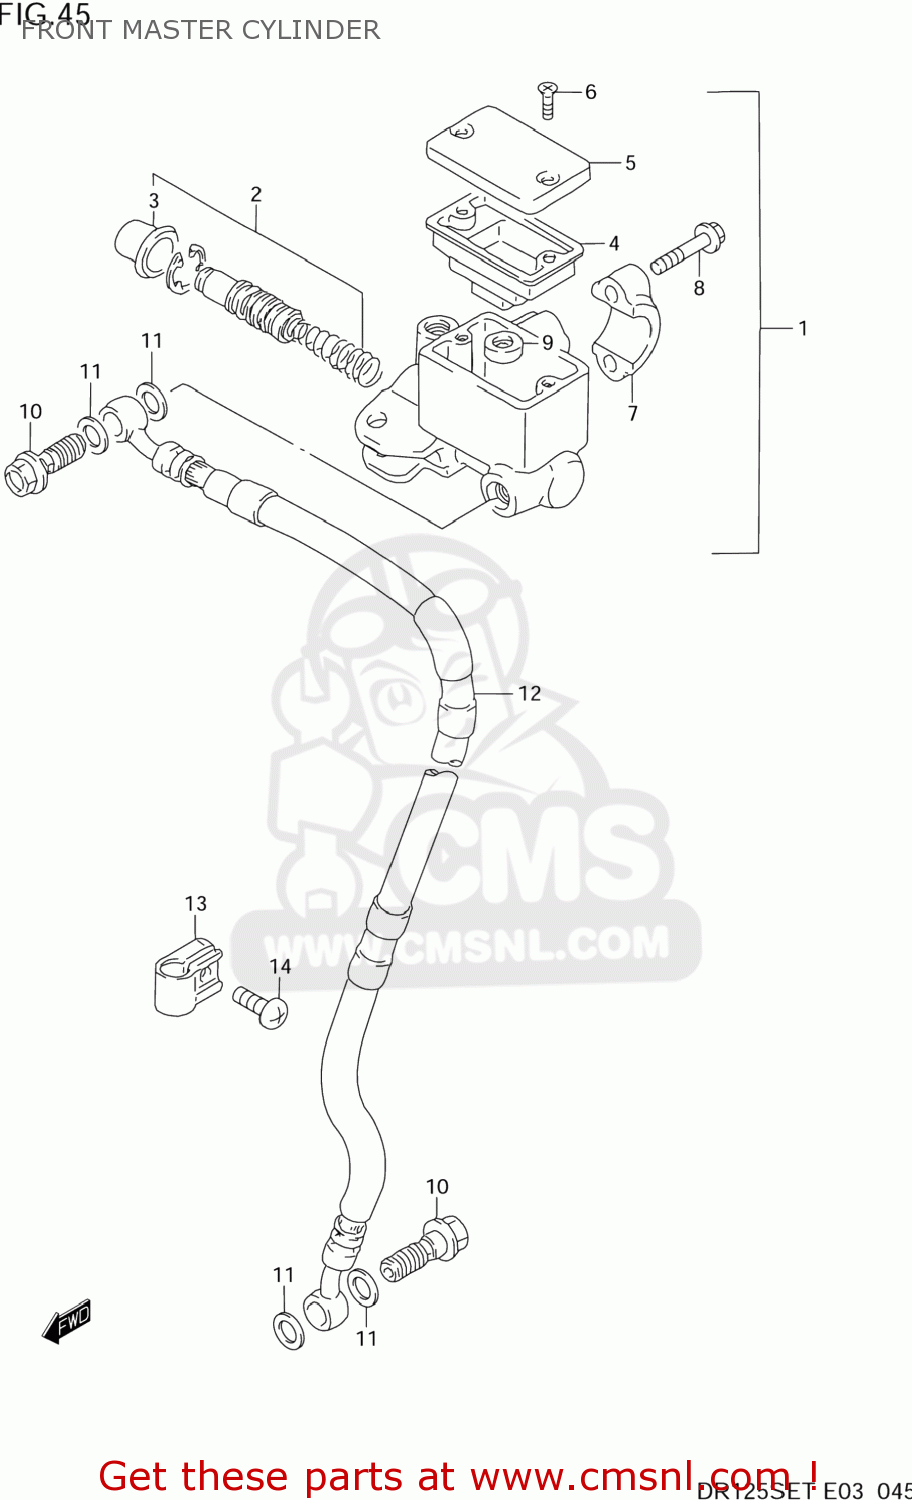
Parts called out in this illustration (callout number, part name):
1	CYLINDER ASSEMBLY,FRONT MASTER
2	PISTON/CUP SET
3	BOOT
4	DIAPHRAGM
5	CAP
6	SCREW
7	HOLDER
8	BOLT
9	SEPARATOR
10	BOLT UNION
11	WASHER(10X15X1.5)
12	HOSE COMP,FRONT BRAKE
13	CLAMP,BRAKE HOSE
14	SCREW
